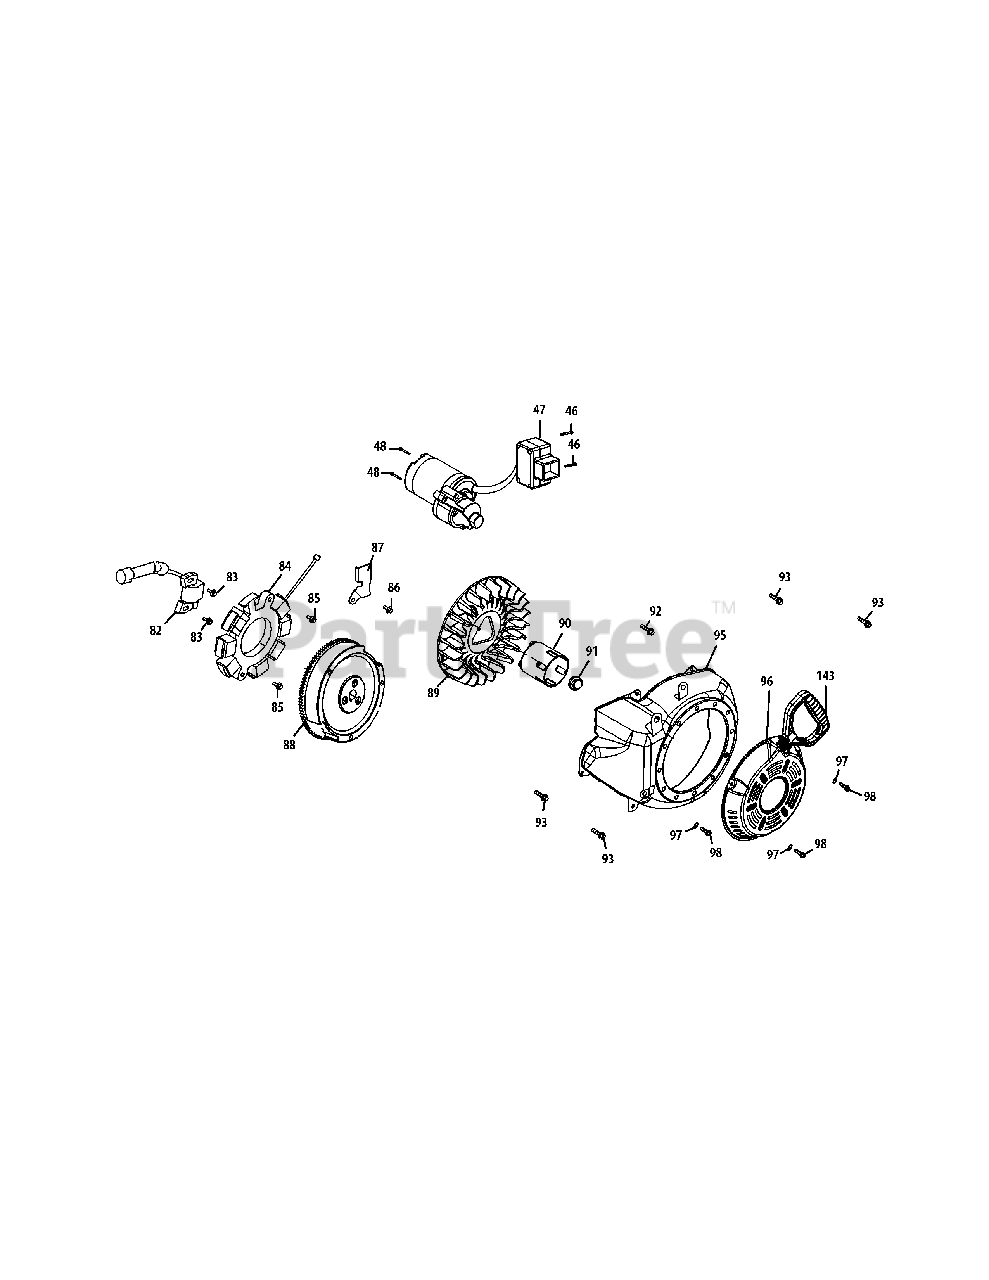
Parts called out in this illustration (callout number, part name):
46	Bolt M4×55
47	Electric Starter
48	Bolt M8×55
82	Ignition Coil Assembly
83	Ignition Coil Bolt
84	Stator
85	Bolt M6×30
86	Bolt M6×8
87	Alternator Wire Clamp Brkt
88	Flywheel
89	Fan, Cooling
90	Starter Cup
91	Nut, Special,M16×1.5
92	Bolt M6×16
93	Bolt M6×12
95	Blower Housing
96	Recoil Starter
97	Washer
98	Bolt M6×10
136	Heater Box
137	Choke Assembly
138	Lock Washer
139	Nut M6
143	Starter Handle
